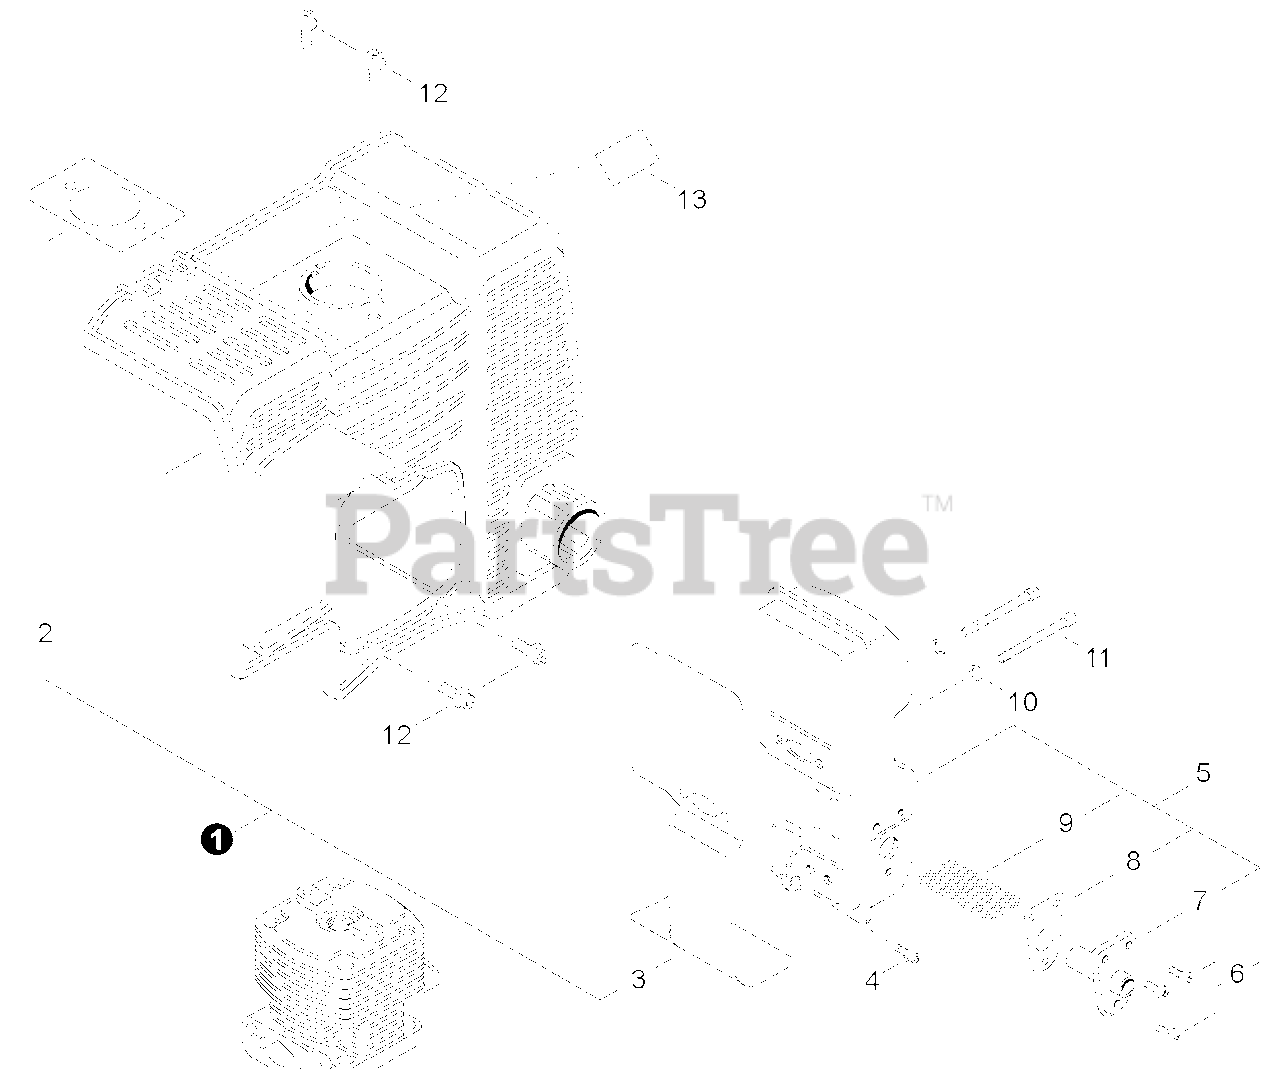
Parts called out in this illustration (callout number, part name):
1	ENGINE COVER KIT
2	EXHAUST SHIELD KIT
3	SHIELD, EXHAUST
4	SCREW - 5X12
5	MUFFLER ASSY
6	SCREW - 4X12
7	GUIDE, EXHAUST
8	GASKET, EXHAUST
9	SCREEN, SPARK ARRESTOR
10	WASHER - 6
11	BOLT
12	SCREW - 5X16
13	LABEL - CAUTION
